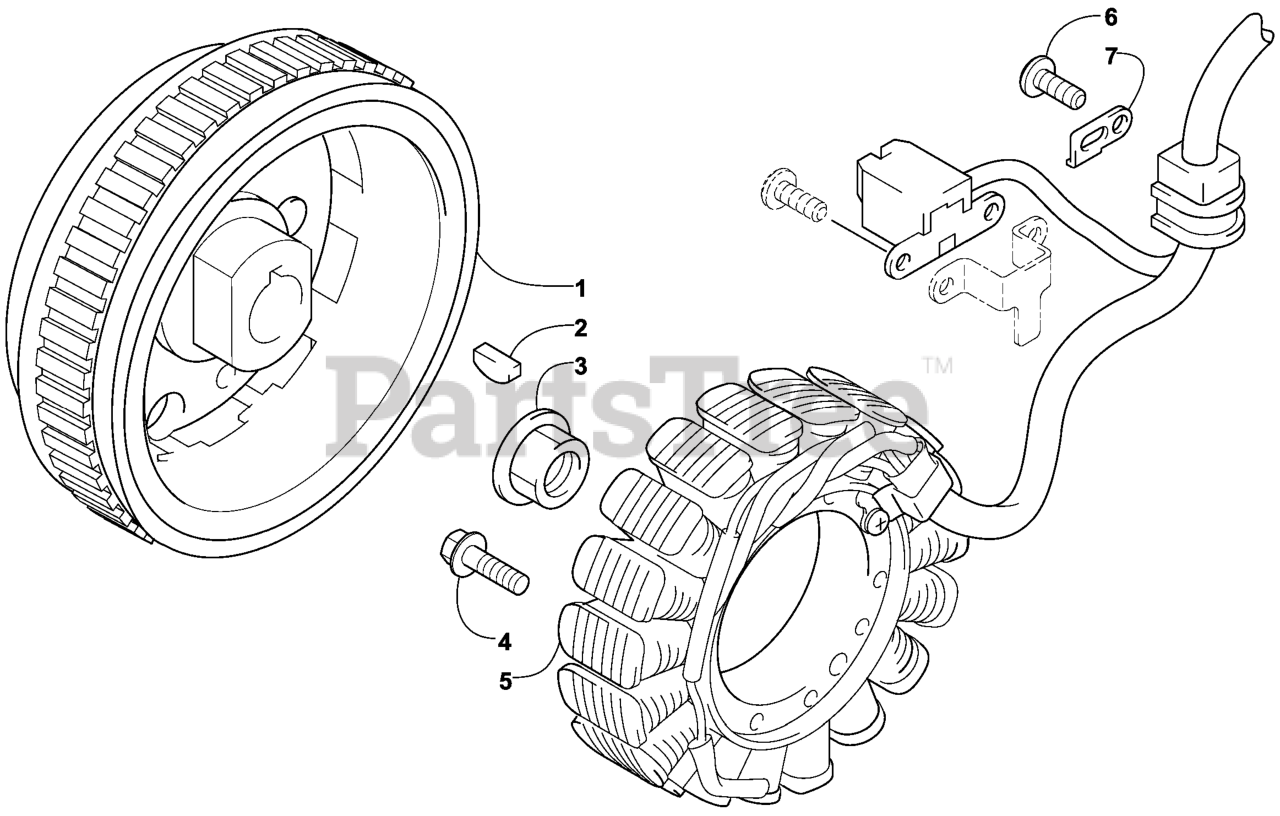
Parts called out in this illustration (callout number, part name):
1	ROTOR-IGNITION, EFI
2	KEY-MAGNETO
3	NUT-HF,
5	STATOR-IGNITION
6	SCREW-TSPNH
